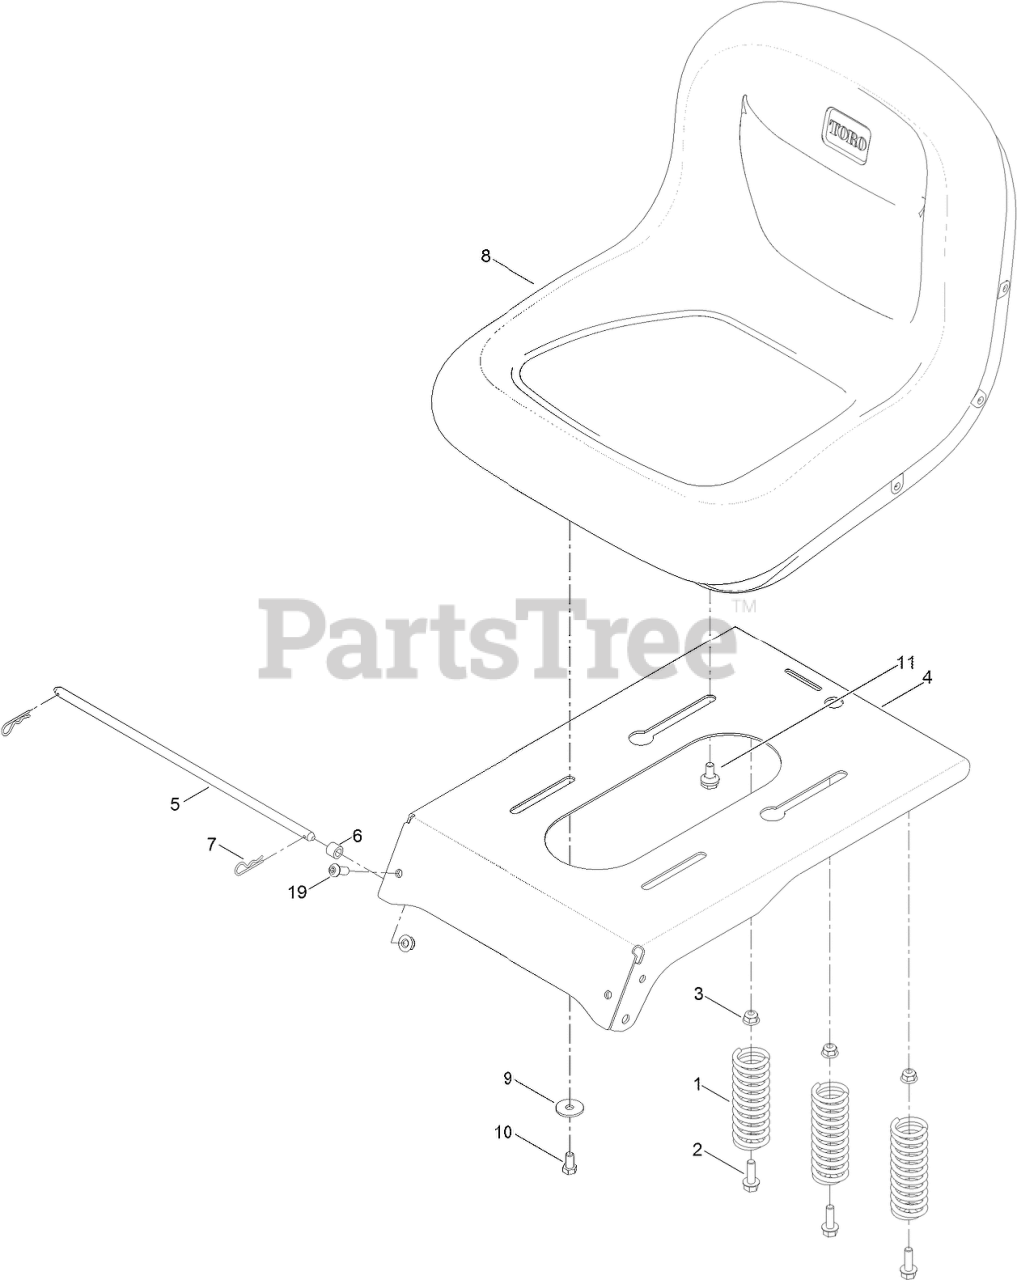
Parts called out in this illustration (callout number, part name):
1	SPRING-COMPRESSION
2	SCREW-HHF
3	NUT-HF, NI
4	PAN-SEAT
5	ROD-STOP
6	BUSHING-LEVER, LIFT
7	PIN-COTTER
8	SEAT-15 INCH
9	WASHER-PIVOT
10	SCREW-HH
11	BOLT-SHOULDER
19	SCREW-HSBH
